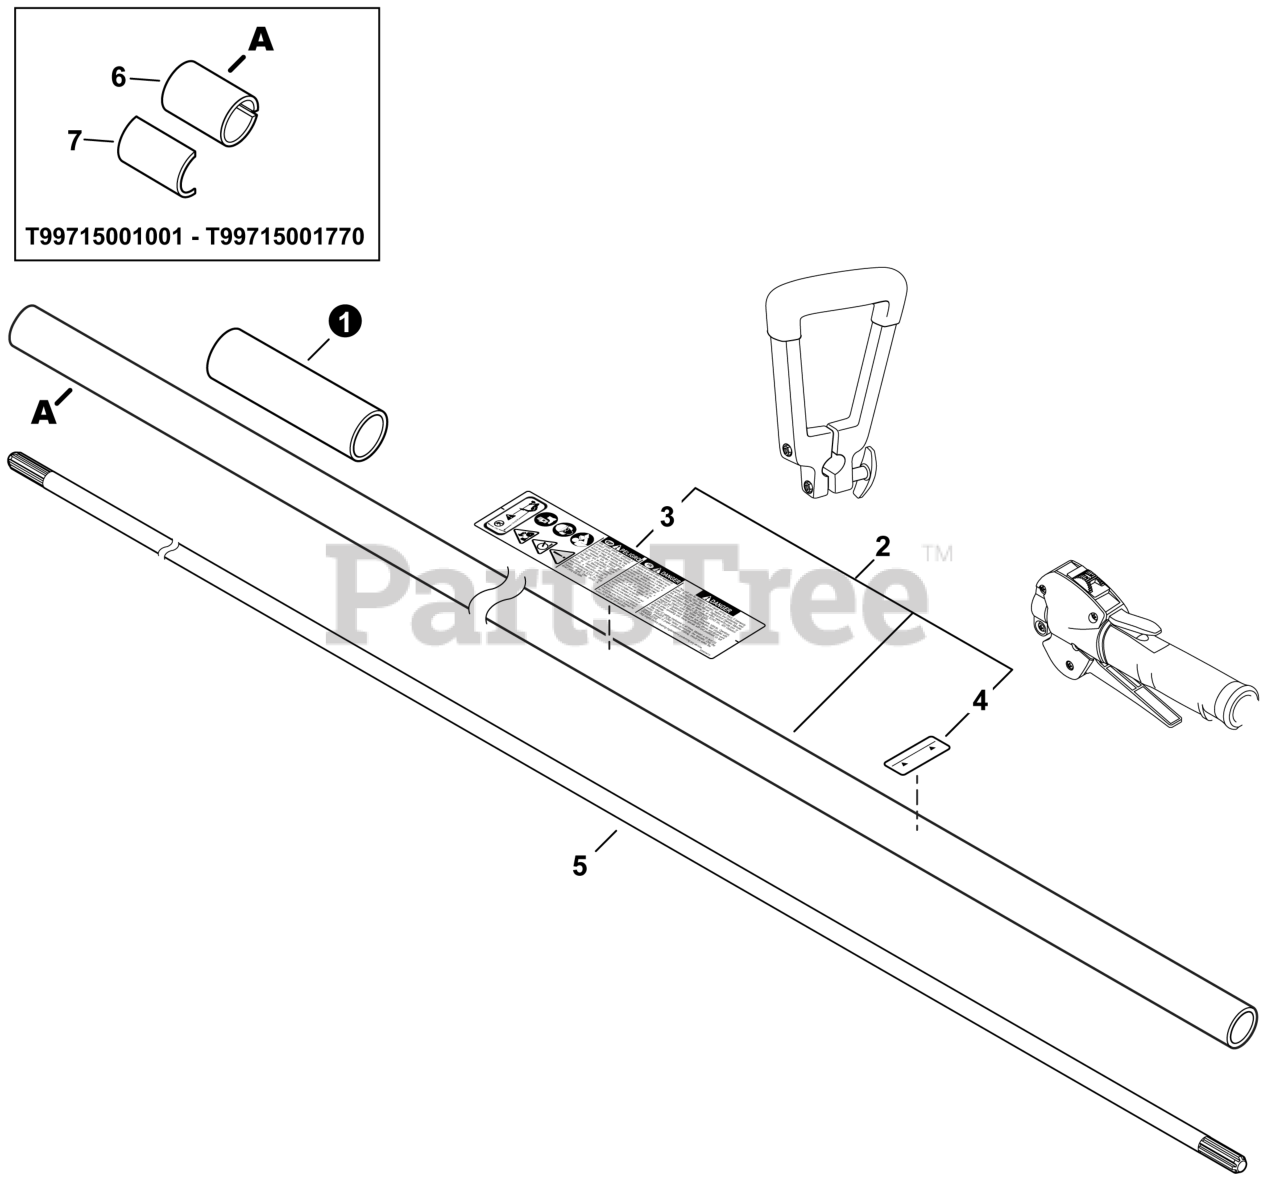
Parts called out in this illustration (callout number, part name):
1	PROTECTOR, MAIN PIPE 25 MM
2	MAIN PIPE ASSY
3	LABEL - CAUTION
4	LABEL - ALIGNMENT
5	DRIVESHAFT
6	COLLAR, MAIN PIPE - 25MM
